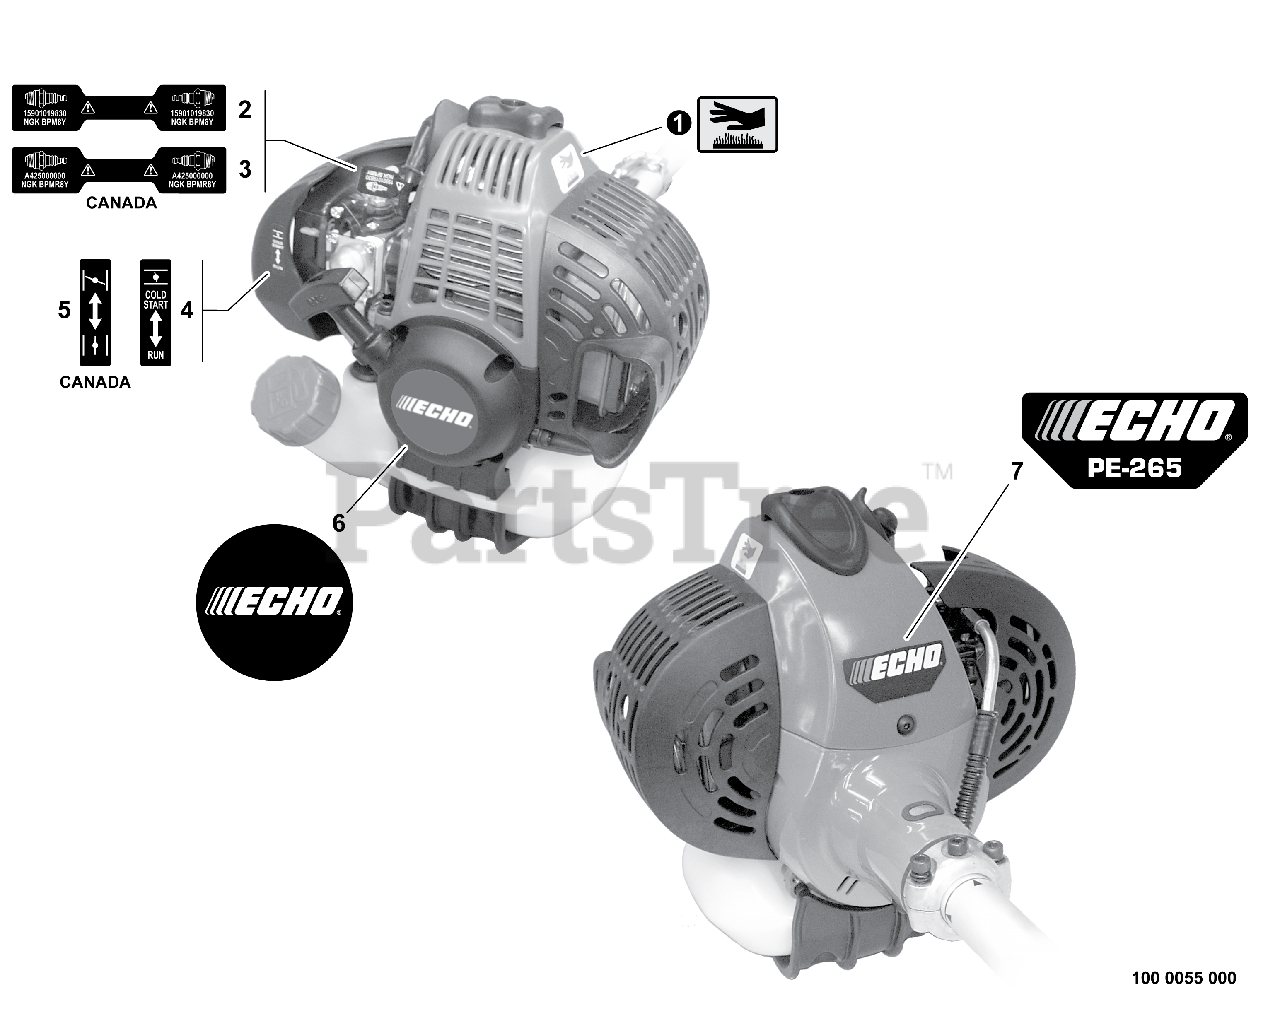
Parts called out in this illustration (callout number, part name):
1	LABEL - HOT SURFACE
2	LABEL - SPARK PLUG -- BPM-8Y
3	LABEL - SPARK PLUG -- BPMR-8Y
4	LABEL - CHOKE
5	LABEL - CHOKE
6	LABEL - ECHO
7	LABEL - MODEL PE-265
